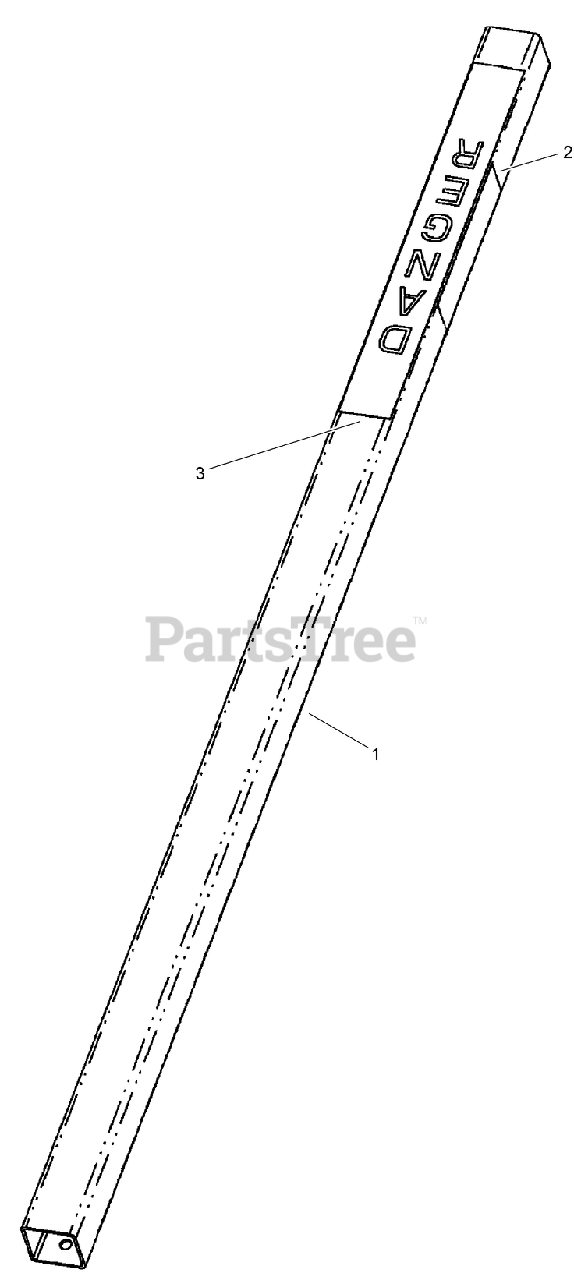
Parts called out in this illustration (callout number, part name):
1	TUBE-Restraint Bar
2	DECAL-Danger, Entanglement Hazard
3	DECAL-Danger
